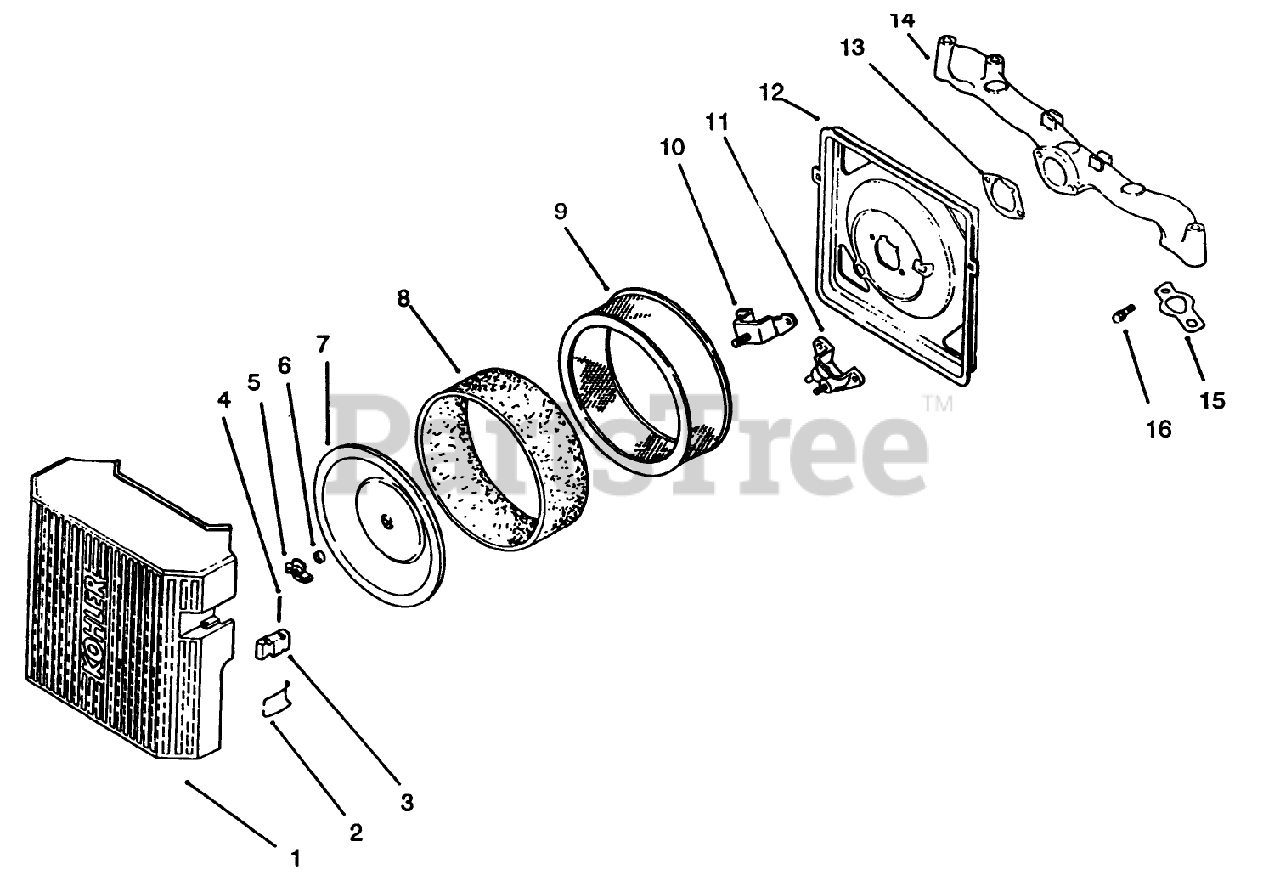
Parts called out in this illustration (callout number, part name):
1	Kit-A/C Cover INCL 2-4 (Only On: 72103;
2	Spring-Latch (Only On: 72103)
3	Latch-Lever (Only On: 72103)
4	Pin-Latch Lever (Only On: 72103)
5	Nut-Wing
6	Seal-Air Intake (Only On: 72103)
7	Cover-Inner Air Cleaner
8	Element-Precleaner
9	Element-Air Cleaner
10	Cup-Fuel Spitback (Only On: 72103)
11	Gasket-Fuel Spitback Cup (Only On: 72103, 72083)
12	Base-Air Cleaner (Only On: 72103)
13	Gasket-A/C Base (Only On: 72103, 72083)
14	Manifold-Intake (Only On: 72103)
15	Gasket-Intake Manifold
